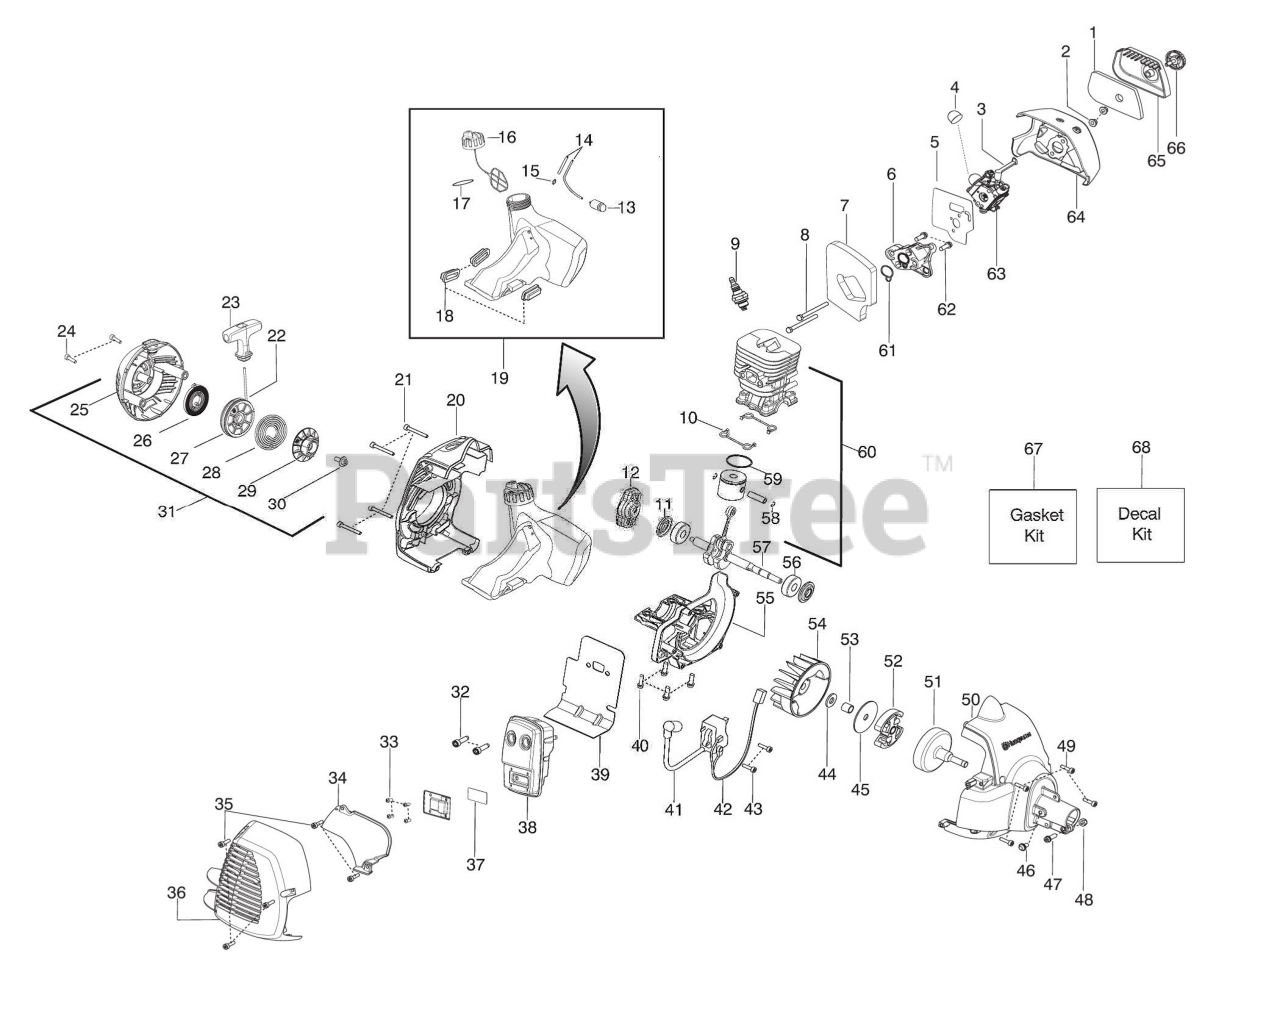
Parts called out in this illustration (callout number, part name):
2	Nut-Carb. Screw
3	Lever - Choke
4	Bulb-Purge
5	Kit-Carb. Gasket
6	Adaptor-Carb.
7	Foam-Gasket
9	Plug-Spark (RCJ-6Y)
10	Seal-Cylinder
11	Seal-Crankshaft
12	Assy-Starter Pawl
13	Assy-Fuel Filter
14	Kit-Fuel Line
15	Fitting-Fuel Line
16	Assy-Cap w/ret.
17	O-ring - Fuel Cap
18	Isolator-Tank
19	Kit-Fuel Tank Assy.
20	Shroud-Rear
22	Kit-Rope
23	Handle-Starter
25	Starter Hsg. w/eyelet
26	Kit-Spring
27	Kit-Starter Pulley
28	Spring - Driver
29	Pulley-Driver
31	Assy-Starter Hsg.
32	Bolt-Muffler
33	Screw
34	Shield-Heat
36	Guard-Muffler
37	Kit-Spark Arrestor
38	Kit-Muffler
39	Gasket-Paper Met.
41	Module
42	Assy-Leadwire
45	Washer-Clutch
50	Assy-Fan Housing
51	Assy-Clutch Drum
52	Assy-Clutch
55	Crankcase-Cast
57	Assy-Crankshaft
58	Retainer-Piston Pin
59	Ring-Piston
60	Kit-Piston/Cyl.
61	Seal-adaptor
63	Kit-Carb.
64	Air box
65	Cover-Air Box
67	Kit-Gasket
